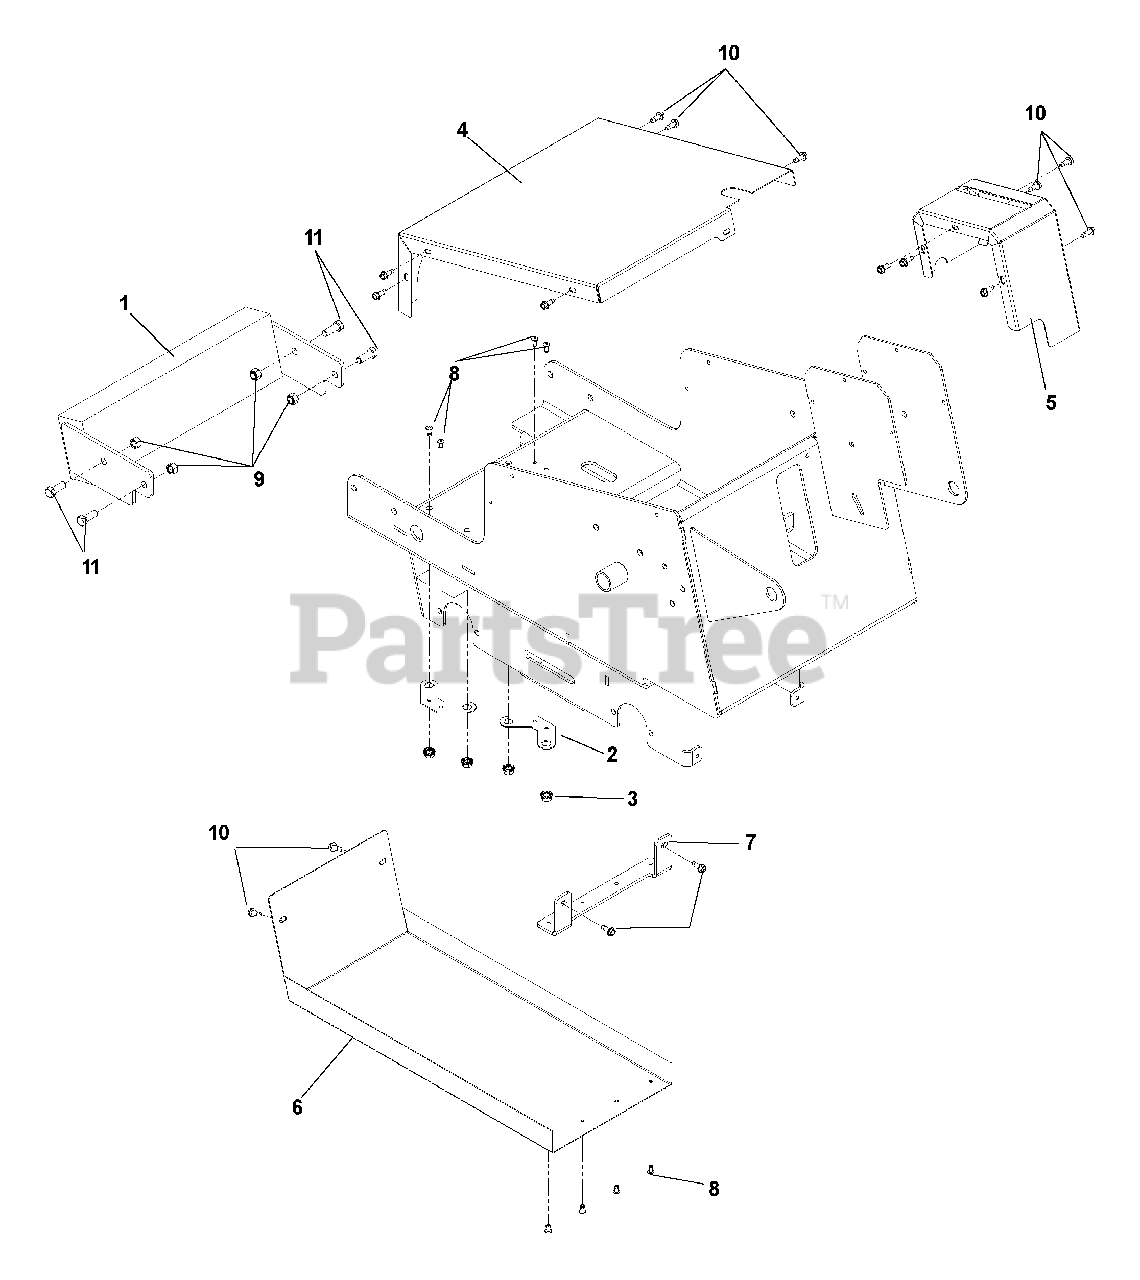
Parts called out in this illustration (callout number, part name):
3	NUT, 5/16-18, NYLOC
4	COVER, TOP
5	COVER, SHIFT
7	END BRACKET
8	RIVET, 3/16
9	NUT, 3/8-16, NYLOC
10	SCREW, 1/4-20 X 5/8, SELF TAP
11	HCS, 3/8-16 X 1, GR5
